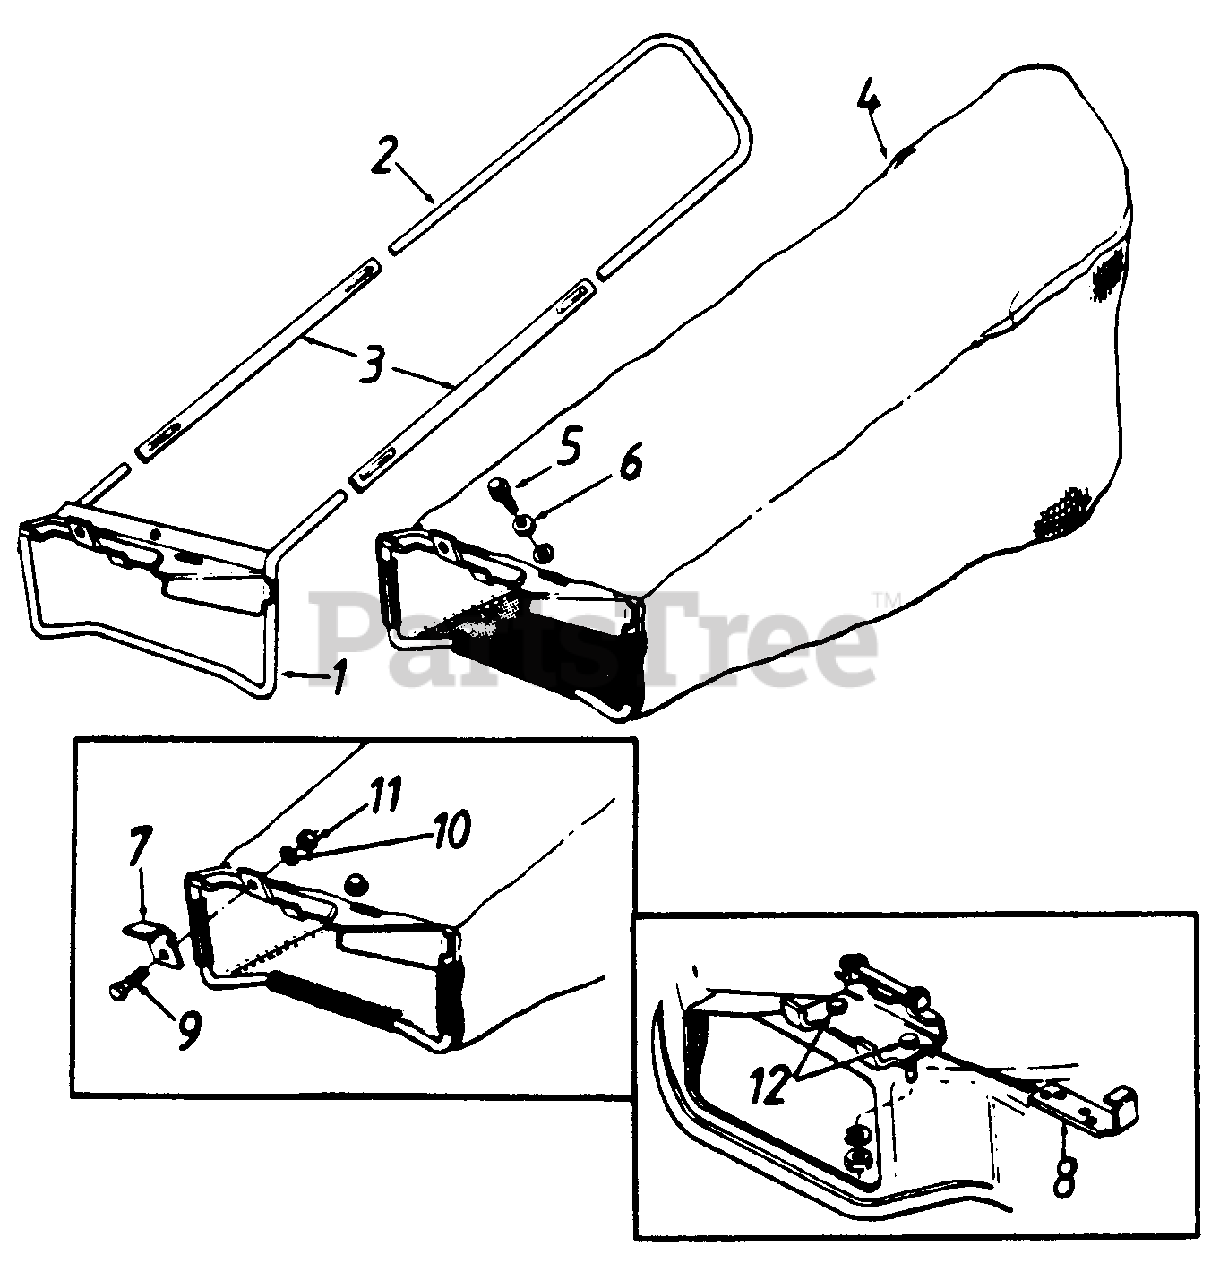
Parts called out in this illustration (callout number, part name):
4	Grass Bag
5	Hex Wash Hd. TT-Tap Scr. 1/4-20 x 5" Lg.
6	Bell-Wash. 1/4" I.D.
7	Deflector Stop
8	Support Plate
9	Hex Bolt 1/4-20 x .5" Lg.
10	L-Wash. 1/4" I.D.
11	Hex Nut 1/4-20 Thd.
12	Hex Bolt 1/4-20 x .62" Lg.
